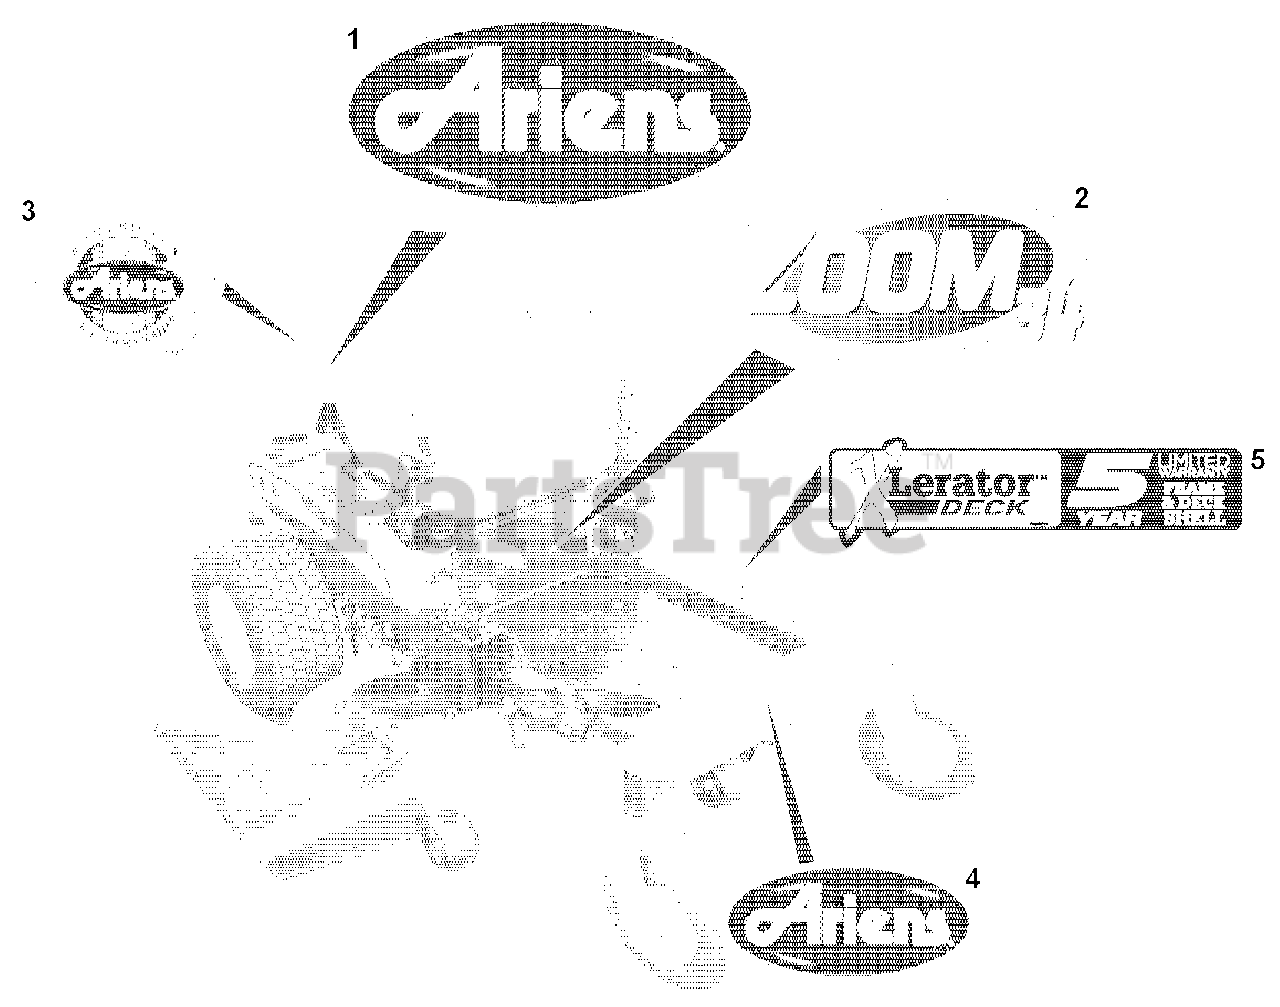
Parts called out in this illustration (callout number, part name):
1	DECAL, ARIENS JEWEL
2	DECAL, ZOOM 34
3	Decal, Ariens Heritage, Large
4	DECAL, ARIENS JEWEL
5	DECAL,DECK WARRANTY-XCEL ARIEN
